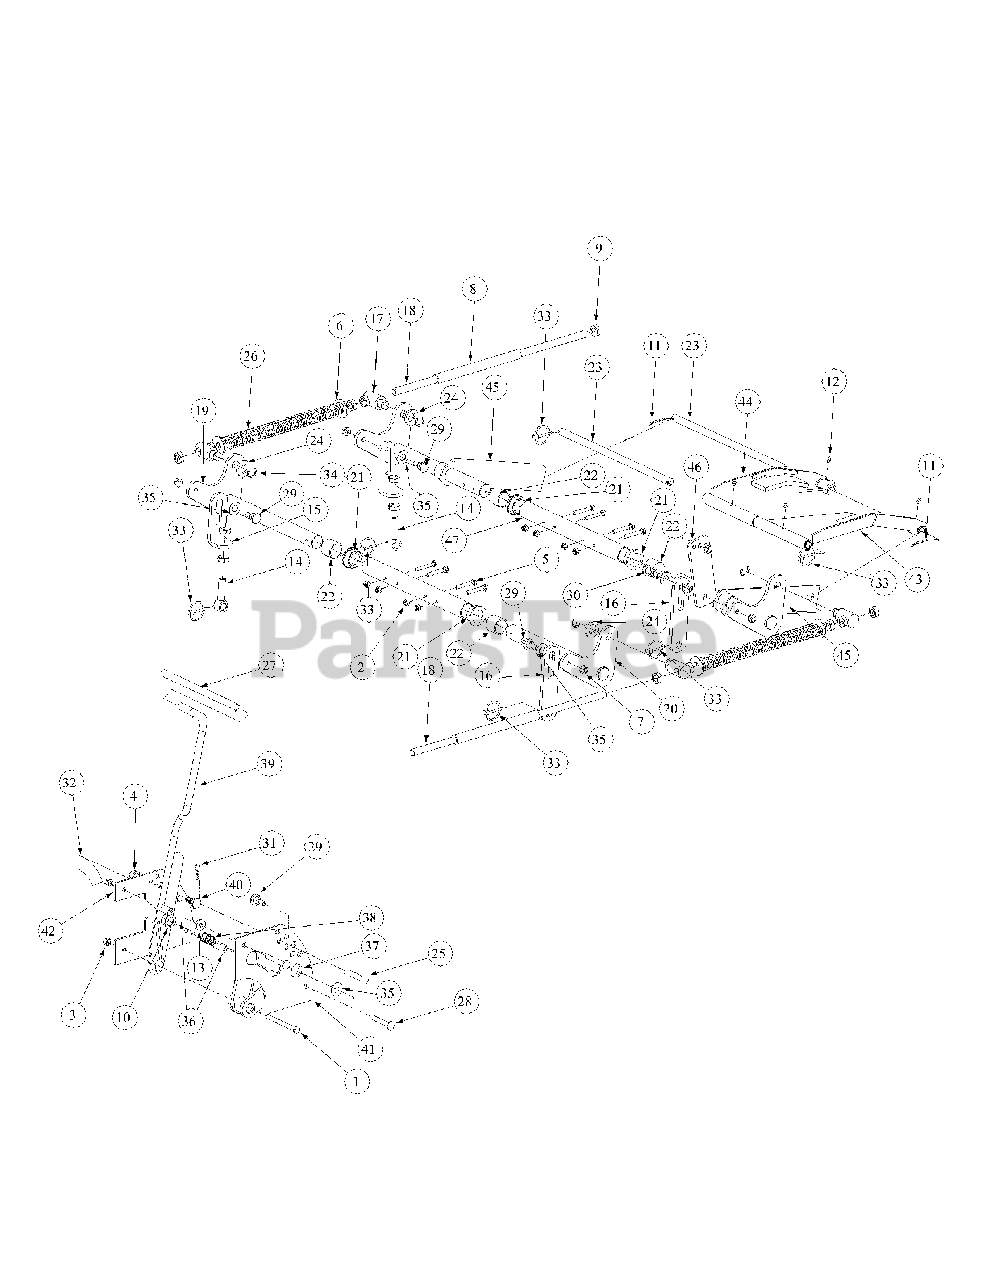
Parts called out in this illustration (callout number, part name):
1	Hex Cap Screw, 3/8-16, 3.75
2	Nut, 5/16-18, Nylock
3	Nylock Insert Lock Nut, 3/8-16
4	Nylock Insert Lock Nut, 1/2-13
5	Hex Cap Screw, 5/16-18 x 2
6	Flat Washer, 5/8
7	Hex Nut, Flange Lock, 3/8-16
8	Hose, 5/8 ID 13/16 OD, 8" LG
9	Jam Nut, 5/8-11
10	Flat Washer, .06, .776, 1.25
11	Cotter Pin, 3/16 x 1-1
12	Grease Fitting, 1/4-28 x 3/16
13	Idler Washer
14	Eye Bolt, 5/8ID
15	Eye Bolt Mount Link, 5/8 ID
16	Deck Link
17	Ferule Lift
18	Lift Connector Rod
19	Bellecrank Weldment Lift, Left Hand
20	Bellecrank Weldment Lift, Right Hand
21	Hex Flange Bearing, 1.25 ID
22	Frame Lift Spacer
23	Front Lift Link, Rod Mount
24	Spacer, .812 ID x .268 Lg.
25	Clevis Pin, .500 Dia. x 2.625 Lg.
26	Lift Compression Spring
27	Lift Handle Grip
28	Carriage Bolt, 3/8-16, 2.75
29	Shoulder Screw, 0.625 OD x .437 Lg.
30	Shoulder Screw, 0.625 OD x .830 Lg.
31	Cotter Pin, .148 x 3.00
32	Decal Height Indicator
33	Linch Pin, 3/16 Dia.
34	E Clip, 3/4 Dia.
35	Nylon Flat Washer, 5/8
36	Spacer, .39 ID x .63 OD x 1.442
37	Lift Pivot Assembly
38	Lift Handle Spring
39	Lift Handle Assembly
40	Shoulder Screw, 5/8 OD x 0.264
41	Outer Lift Index Plate
42	Inner Lift Index Plate
43	Bearing Lift Brace Assembly, Right Hand
44	Bearing Lift Brace Assembly, Left Hand
45	Front Frame Strut Assembly
46	Lift Link Adjustment
47	Lift Shaft Holder
